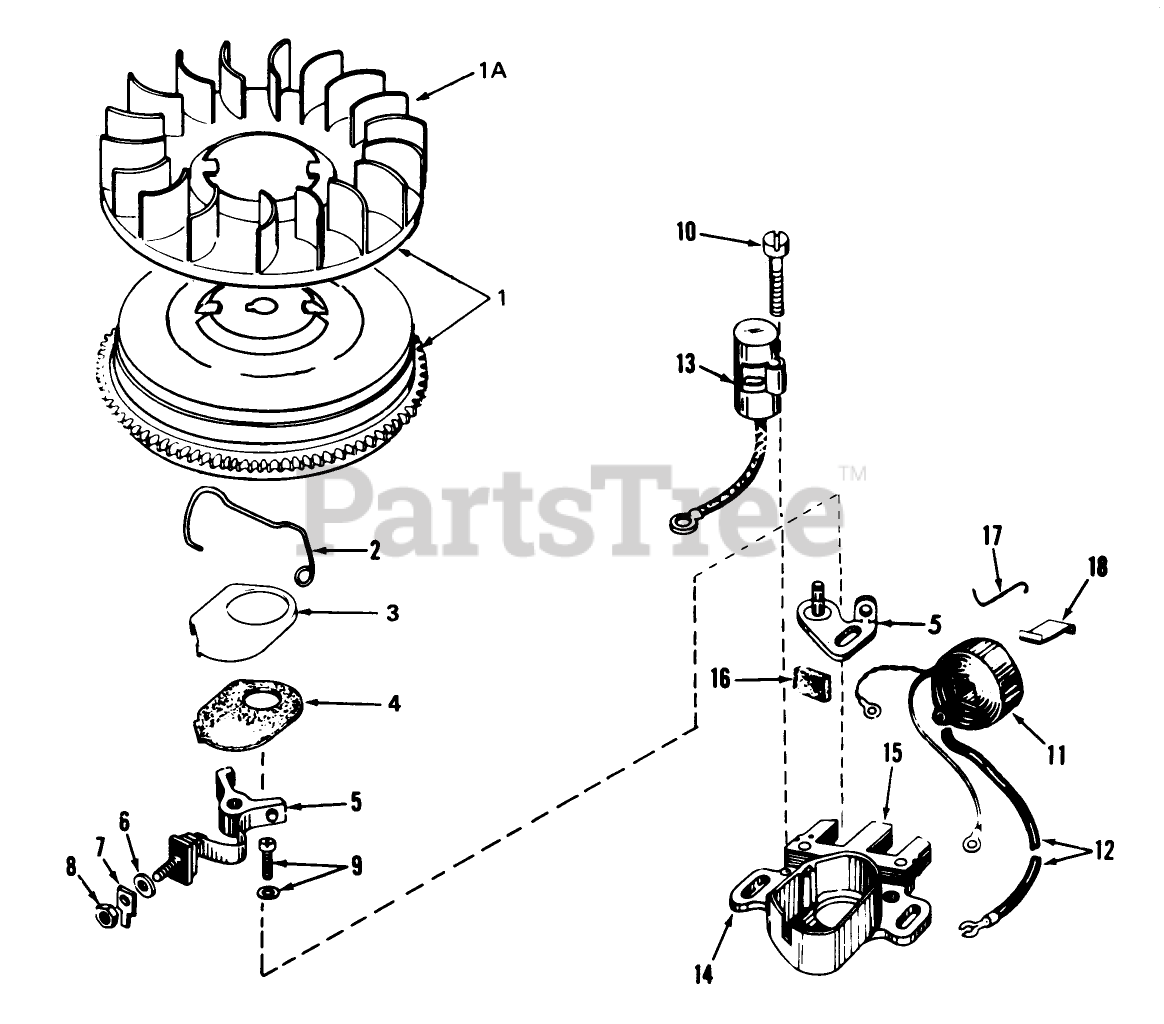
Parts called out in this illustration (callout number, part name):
1	5247/7229/68/R7268/
1A	Fan
2	Spring Breaker Box
3	Cover-Dust
4	Gasket, Dust Cover
5	Breaker Assy.
6	Washer
7	Terminal, Ground
8	DECAL
9	Breaker Screw
10	Condenser Screw
11	Coil Assy. (Incl. No. 12)
12	Wire, Lead
13	Condenser
14	Core Plate
15	Stator Assy. (Incl. Ref. #2 thru 11, 13, 14, 16, 17 19)
16	Felt,Cam Wiper
17	Clip, Coil
18	Spring Coil Wedge
